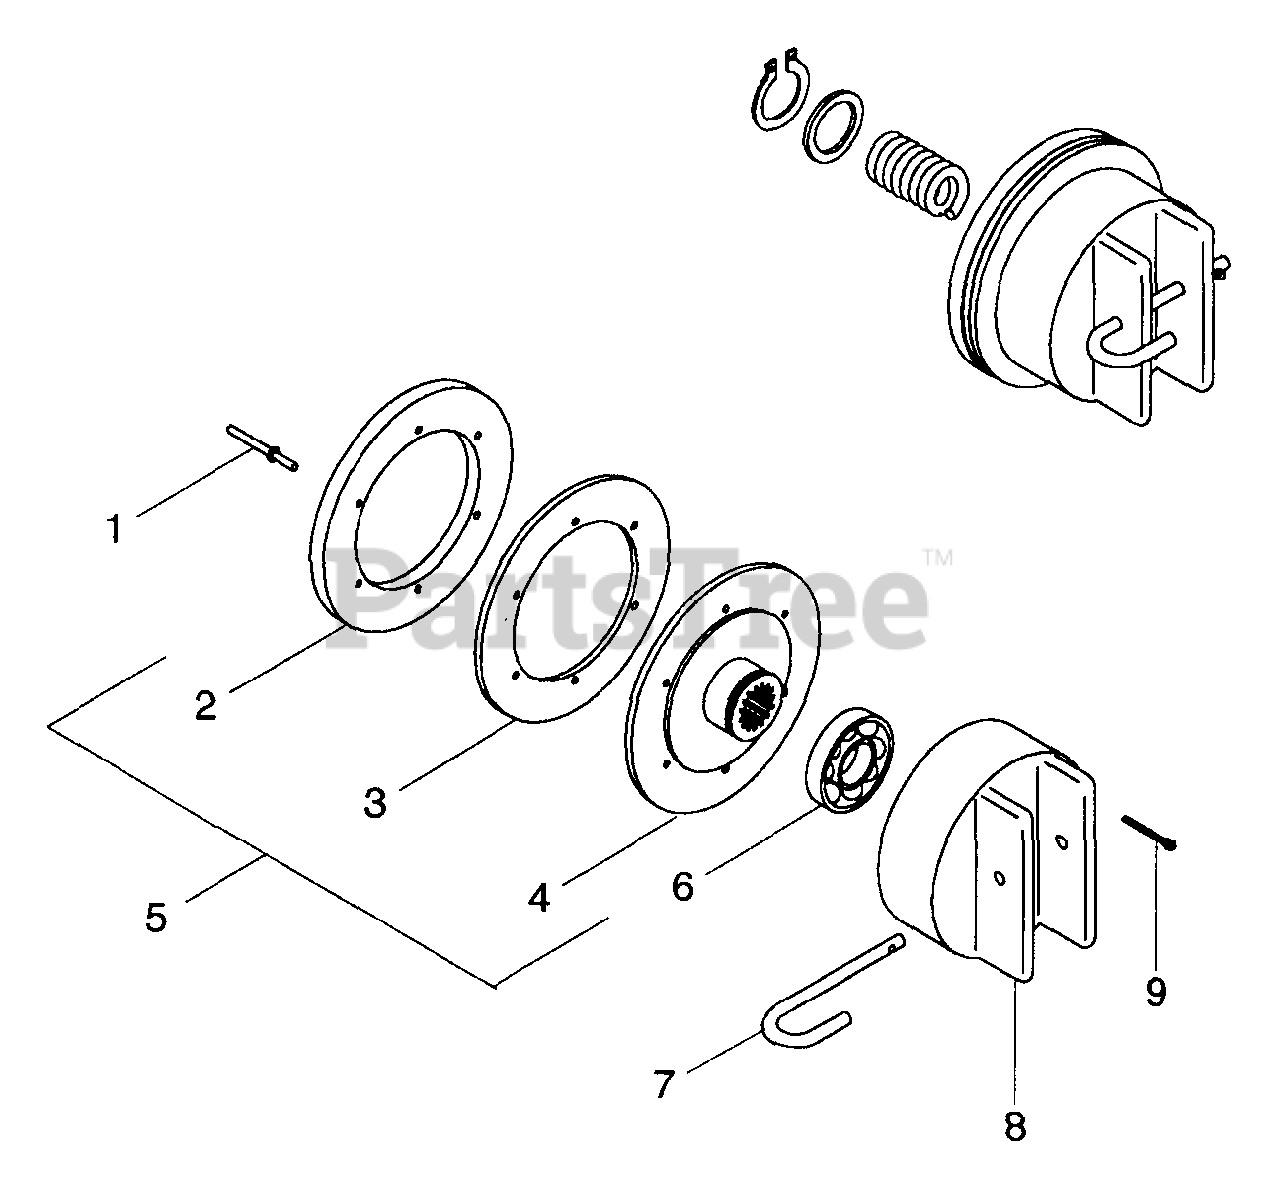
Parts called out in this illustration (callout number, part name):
1	Rivet
2	Lining, Clutch
3	Ring, Clutch
4	Disc, Clutch
5	Assembly, Clutch & Ring
6	Bearing-Ball 1.57 x 3.15 x .71
7	Pin, Clutch Spring
8	Trunion, Fwd-Rev Clutch
9	Pin-Cotter .062 x .75
